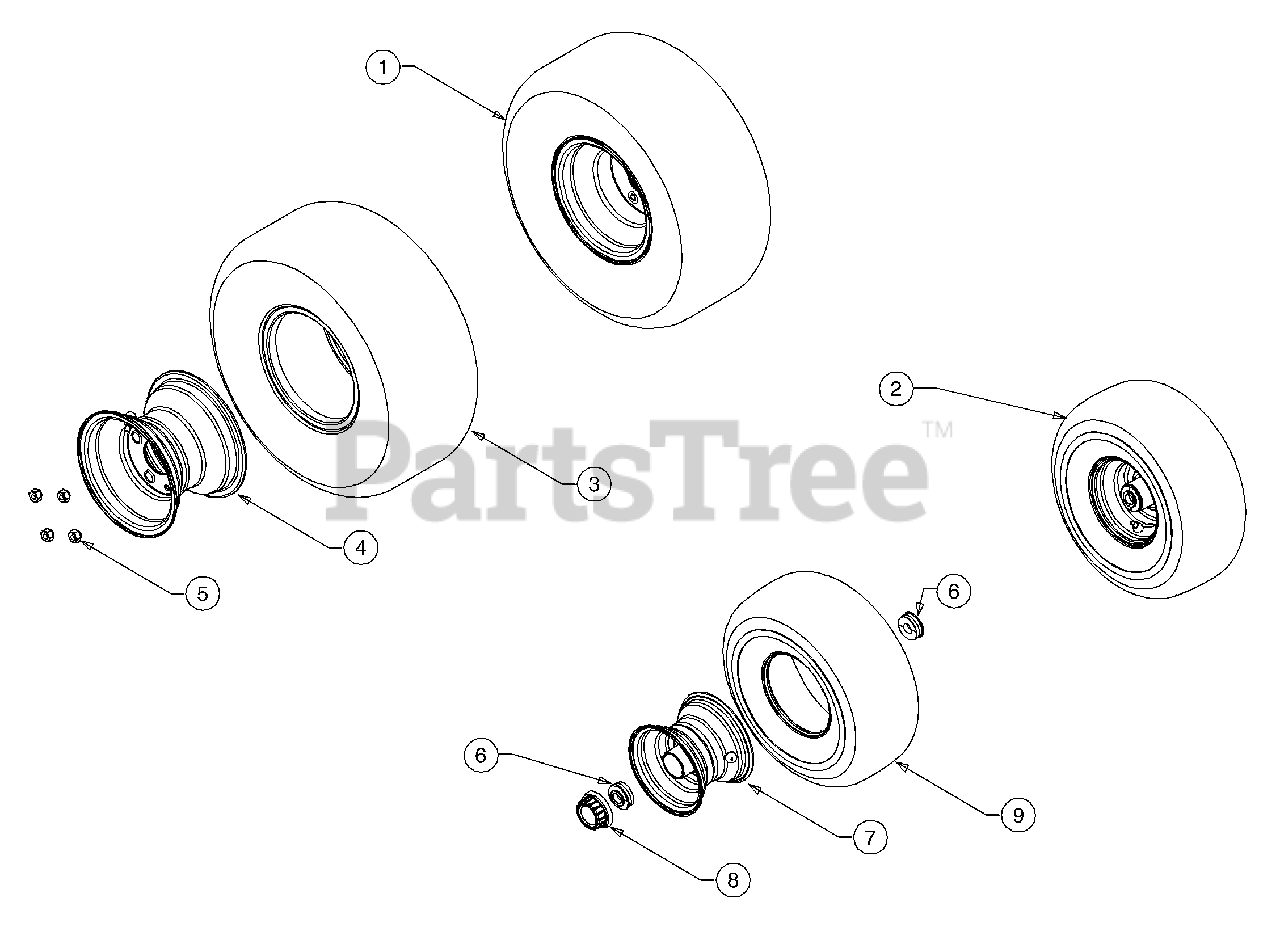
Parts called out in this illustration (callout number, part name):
1	Rim/Wheel Assembly, 20 x 9 x 8 (4-Lug)
2	Wheel, Complete, 15 x 6 x 6
3	Tire, Turf, Cub Cadet 20 x 9 x 8
5	Lug Nut, 7/16-14
6	Bearing, Ball, .75 ID x 1.75 OD
8	Hub Cap
9	Tire, Turf, Cub Cadet 15 x 6 x 6
